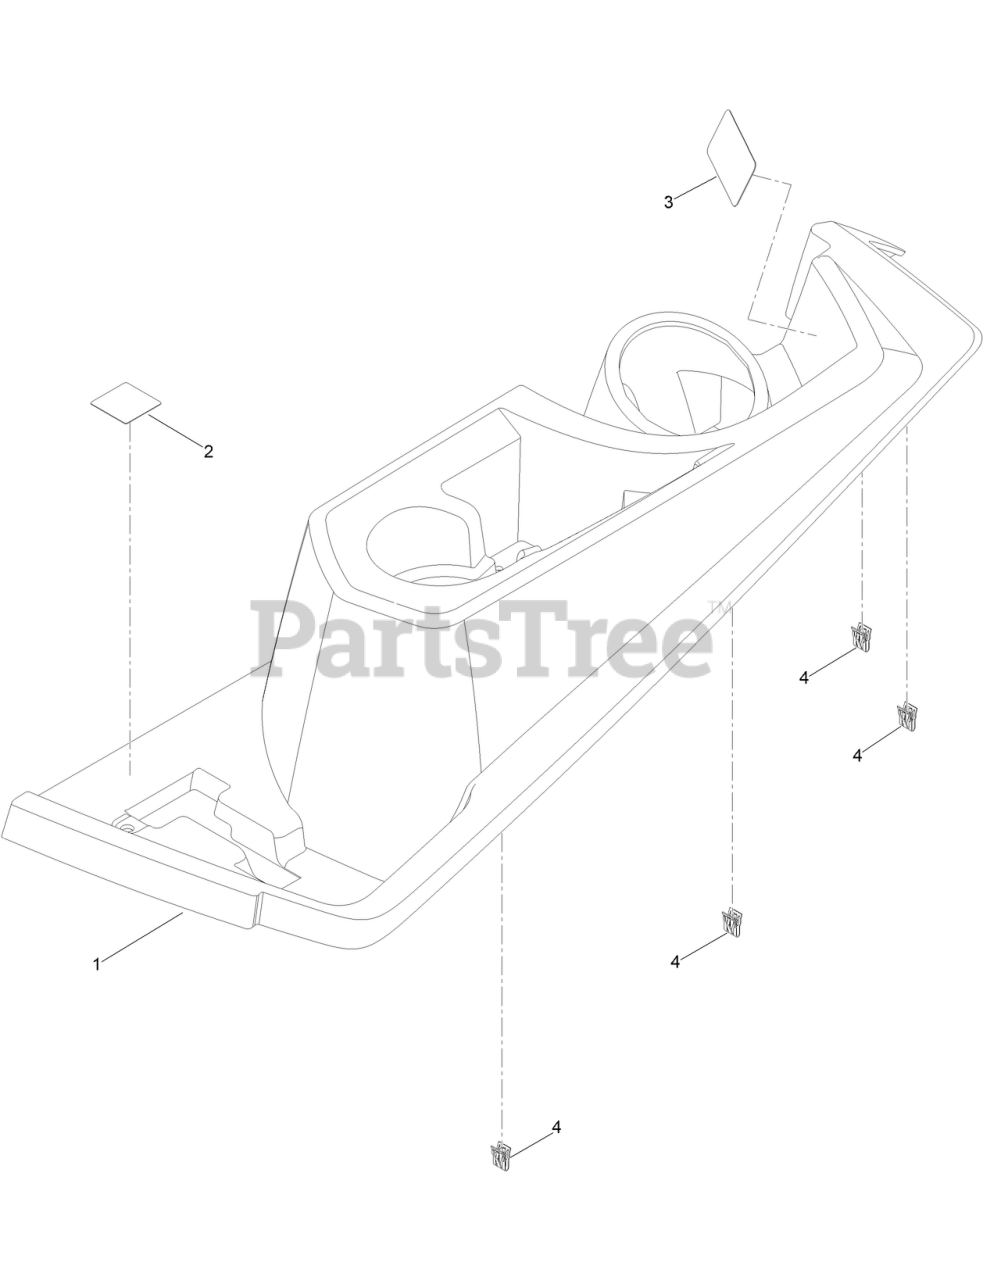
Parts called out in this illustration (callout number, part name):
1	POD-UPPER, LH
2	DECAL-CONTROL, LH
3	DECAL-FILL, FUEL
